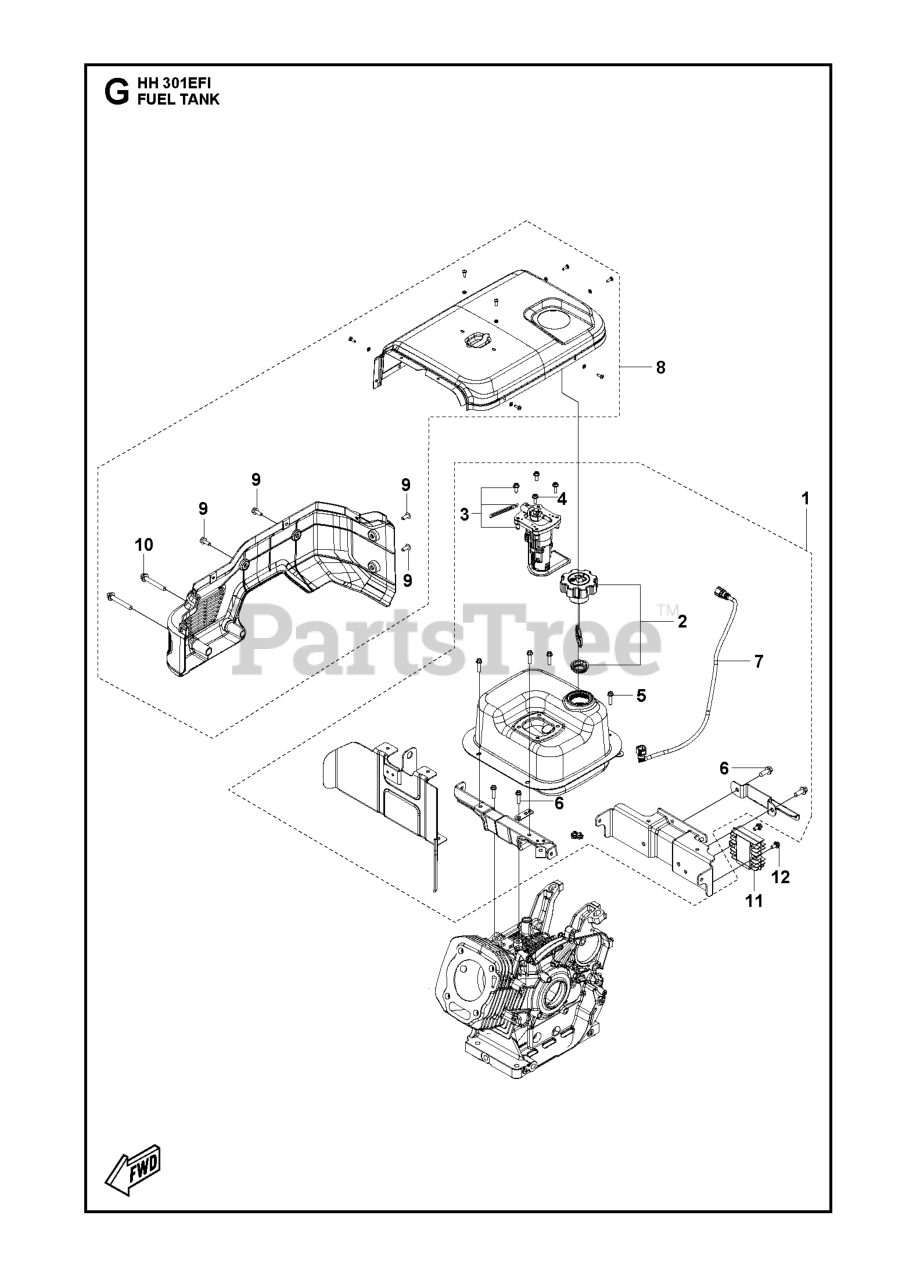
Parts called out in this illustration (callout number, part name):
1	FUEL TANK ASSY
2	FUEL CAP ASSY
3	FUEL PUMP FUEL PUMP ASSY
4	BOLT
5	BOLT
6	BOLT
7	TUBE FUEL TUBE
8	COVER KIT FUEL TANK COVER KIT
9	BOLT
10	BOLT
11	REGULATOR VOLTAGE REGULATOR
12	BOLT
